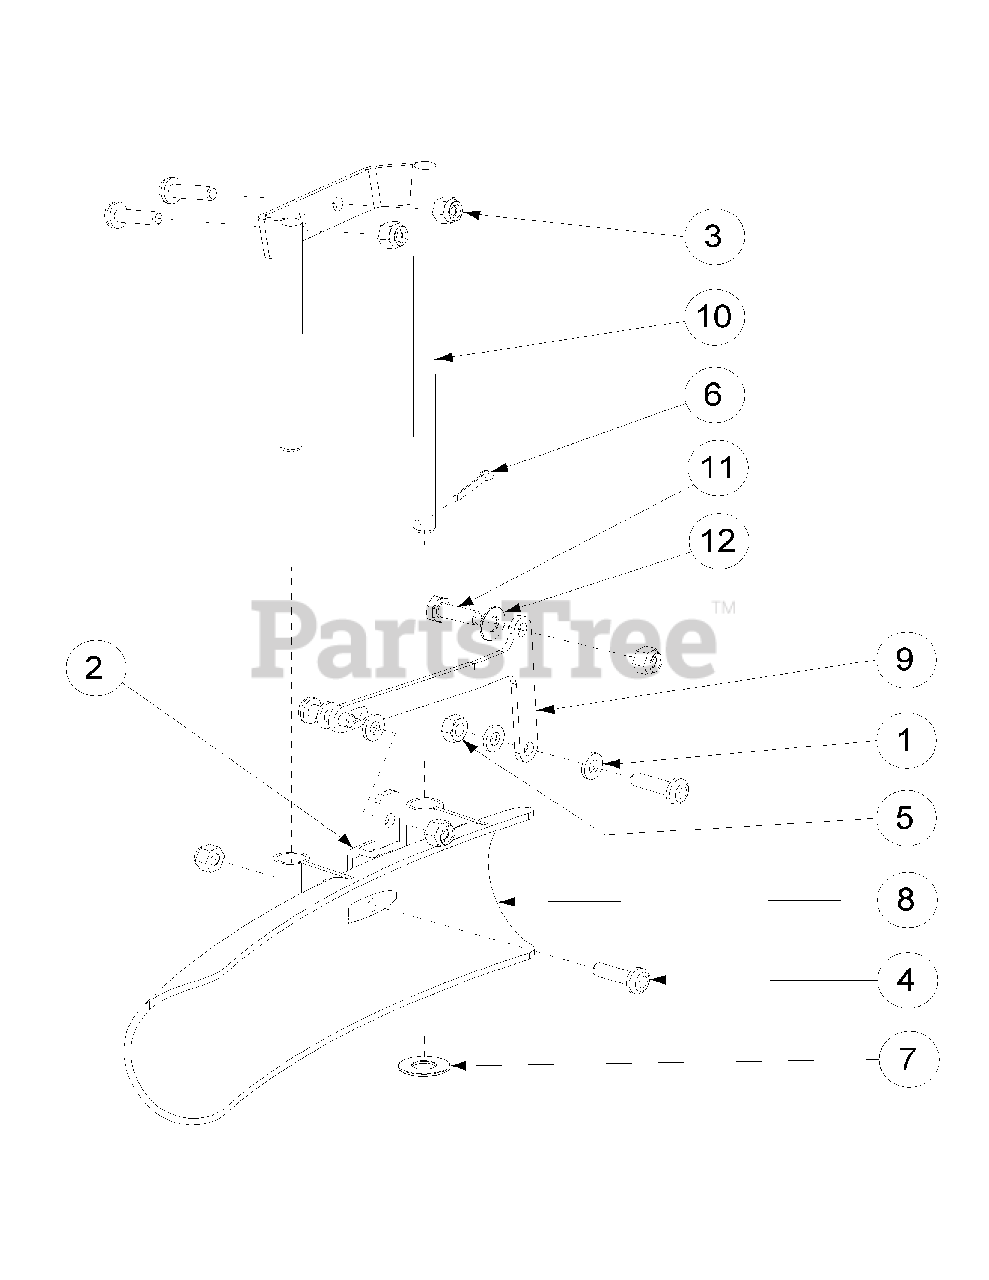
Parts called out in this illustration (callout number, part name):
1	Flat Washer, 1/4 Nylon
2	Offset Deflector Bracket
3	Nylock Nut, 1/4-20
4	1/4 -20 x 7/8 Pan Head Mach Screw
5	Hex Nut, 1/4-20
6	Cotter Pin, 1/8 x 1
7	Flat Washer, 3/8
8	Deflector Tube, Plastic Only
9	Deflector Mount Lever
10	Deflector Mount Weldment
11	HHCS: 1/4-20 x .75
12	Flat Washer, 1/4" SS
